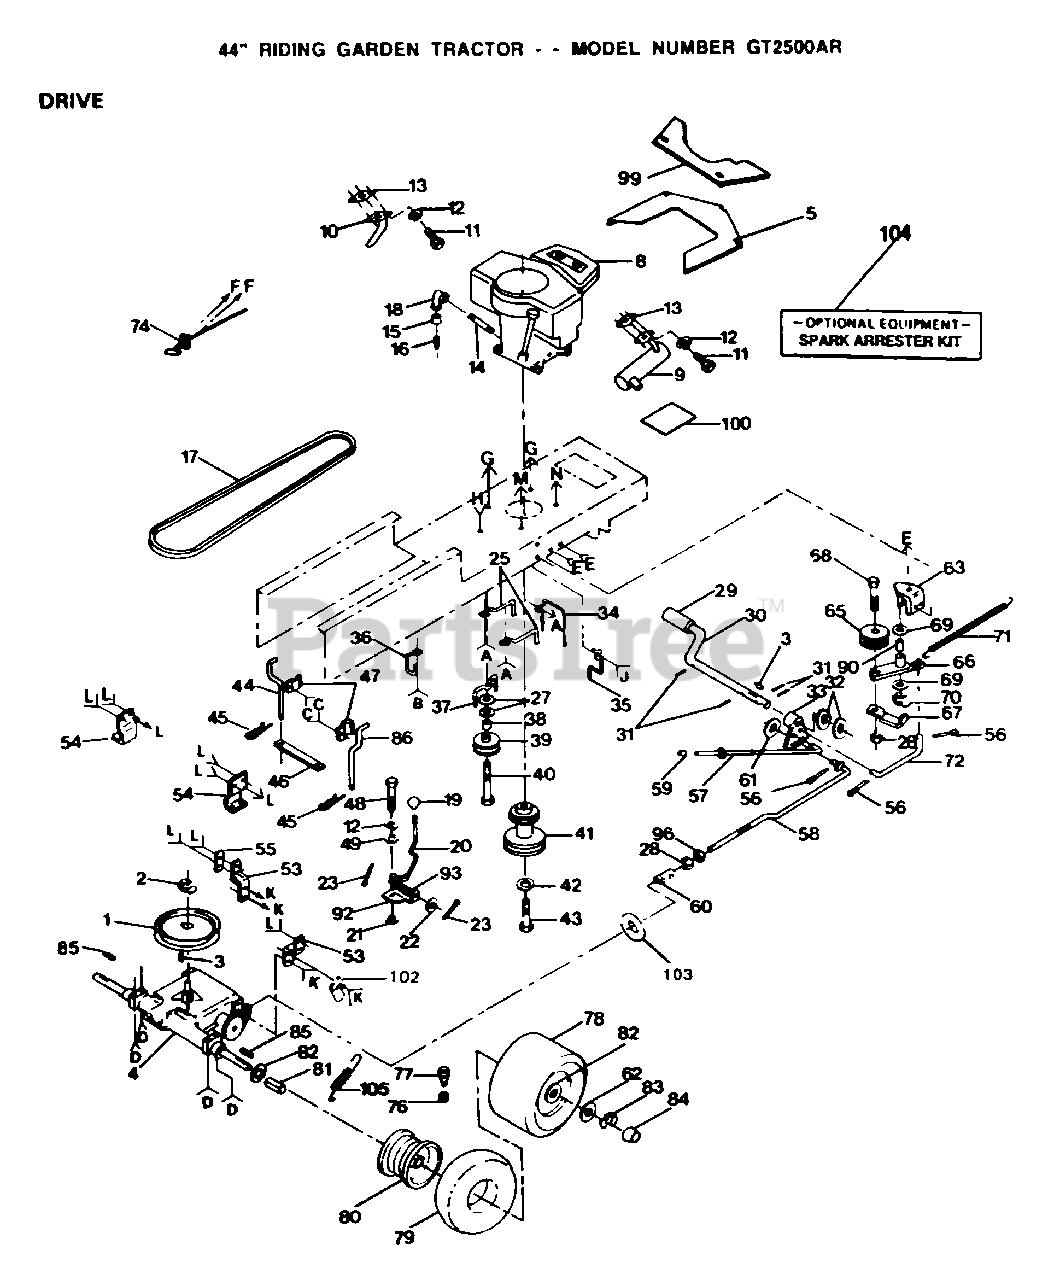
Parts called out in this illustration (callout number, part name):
1	PULLEY TRANSAXLE
2	RING
4	TRANSAXLE PEERLESS
10	EXHAUST TUBE T
12	LOCKWASHER
14	PIPE NIPPLE
16	PLUG T
18	STREET ELBOW LT
19	KNOB T (1/2-HOLE)
21	WASH-SHFT PLT LT
22	WASHER
23	PIN COTTER 1/8
25	"KEEPER,BLT ENG LT"
27	WASHER
29	PEDAL COVER T
30	FOOT SHAFT PEDAL
32	WASHER
33	ARM BRAKE LT
34	BELT GUIDE
35	BELT GUIDE
37	BELT KEEPER LT
38	SPACER T
40	BOLT
42	LOCKWASHER
45	SPRING.RETAINER
46	STRAP LOCATOR
47	CLAMP LT
49	WASHER LT
53	STRAP TORQUE
54	BRACKET LT
55	PLATE-STRAP LT
56	COTTER PIN
58	ROD BRAKE
59	PLUNGER CAP T
60	SPRING ROD LT
61	WASHER
62	WASHER T
69	WASHER LT
70	KLIP RING
71	"SPRING, RETURN LT"
72	"LINK, CLUTCH T"
76	VALVE CAP
77	VALVE STEM LT
79	TUBE.18X9.5-8
81	SPACER HYT
82	WASHER
83	E RING HYT
84	HUB CAP
85	SQ KEY STD
90	"LY, BEARING"
92	PLATE SHIFT LT
93	SPRING LT
96	NUT
99	REAR BAFFLE T
102	CLIP T
103	WASHER
